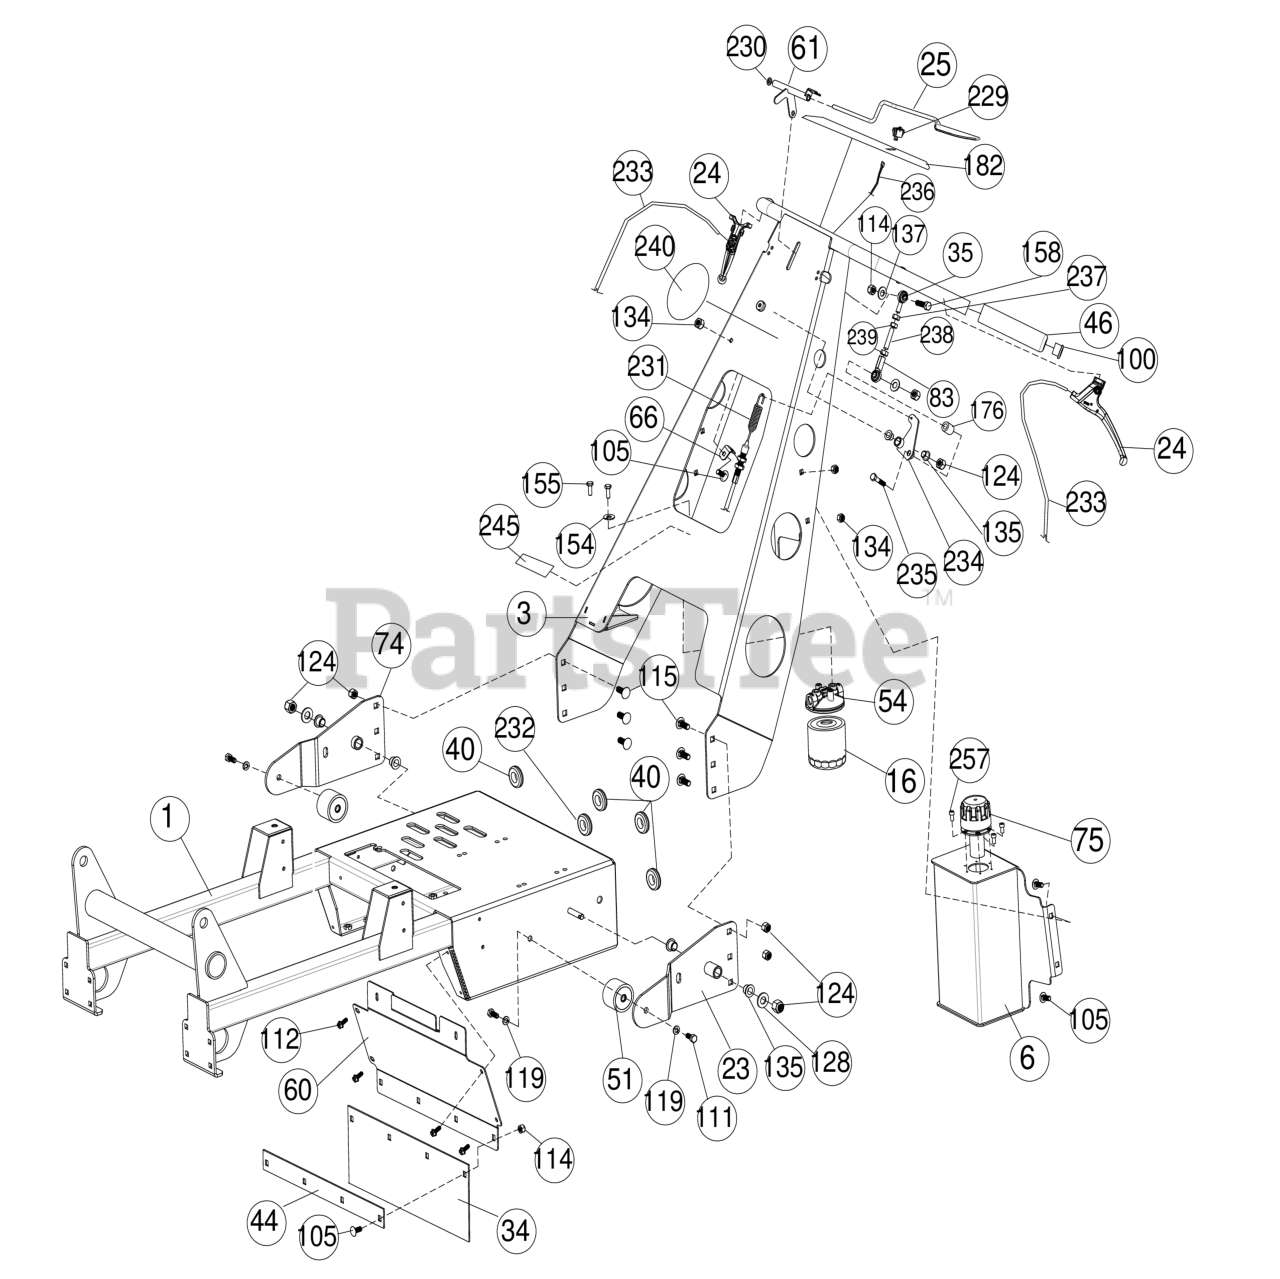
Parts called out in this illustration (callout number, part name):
1	ENGINE BASE WA W/LABELS AE1300H
3	HANDLE WA W/LABELS AE1300H
6	TANK OIL WA AE900H
16	FILTER SPIN ON
23	BRACKET LH HANDLE MOUNT WA
24	CONTROL MAGURA
25	BAIL ASSY AE900
34	DEFLECTOR RUBBER OS900SP
35	SPHERICAL ROD END FEMALE 5/16"-24 LFT
40	GROMMET 1" HOLE
44	BAR CLAMP DEFLECTOR
46	GRIP HANDLE
51	RUBBER HANDLE MOUNT
54	MOUNT OIL FILTER
60	GUARD TRANSAXLE FRONT
61	BELL CRANK BAIL WA
66	BRACKET CLUTCH CABLE
74	BRACKET RH HANDLE MOUNT WA
75	RESERVOIR CAP
83	SPHERICAL ROD END MSF-5
100	PLUG TUBE INSERT 1" OD
105	BOLT CARRIAGE 5/16"-18 X 3/4" ZP
111	SCREWCAP 3/8"-16X3/4" HCS ZP
112	SCREW SELF TAP 1/4"-20 X 5/8" HWH TYPE F
114	NUT LOCK 5/16"-18 HEX Z/P
115	BOLT CARRAIGE 3/8-16 X 1" ZP
119	WASHER LOCK 5/16 ST MED
124	NUT LOCK 3/8"-16 HEX
128	WASHER 5/16" FLATWASHER Z/P
134	NUT FLANGE 5/16"-18 ZP
135	BUSHING .500" ID
137	WASHER 5/16" SAE Z/P
154	WASHER LOCK 1/4" S/T MED
155	SCREWCAP 1/4"-20X1/2" HCS ZP
158	SCREWCAP 5/16"-18 X 1" HCS ZP
176	SPACER ENGINE SIDE
229	SWITCH ENGINE KILL TOGGLE
231	SEE: 362276-S
232	GROMMET 1.25" HOLE
233	CABLE SPEED CONTROL RH SERVICE
234	BELLCRANK CABLE WA
235	SCREWCAP 5/16"-18X1 1/2" HCS ZP
236	HARNESS WIRE KILL SWITCH
237	NUT 5/16"-24 LEFT HAND FIN HEX ZP
238	JACKSCREW 5/16"-24 RT AND LFT
239	NUT 5/16"-24 FIN HEX Z/P
240	LABEL INGROUND TURNING LOGO
245	LABEL HOT SURFACE
257	SHCS 10-32 NF 1/2" SS
